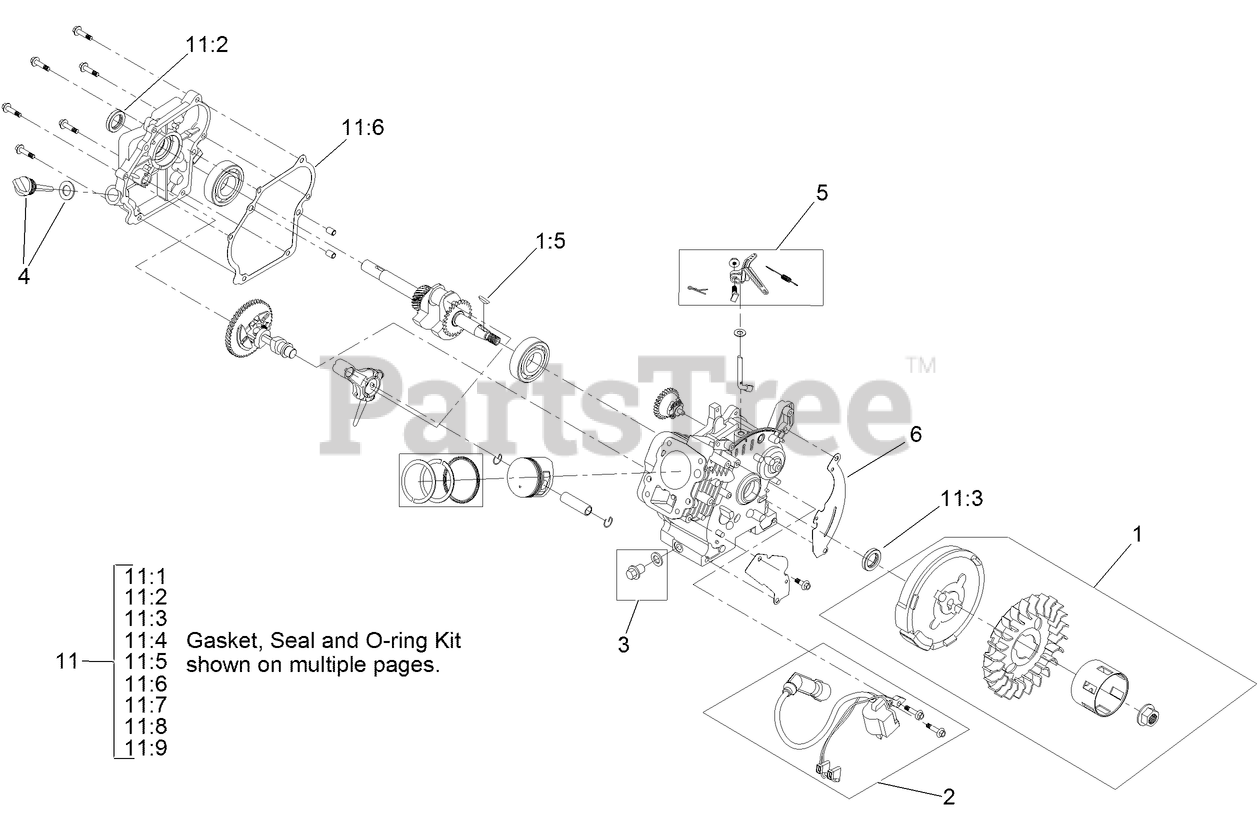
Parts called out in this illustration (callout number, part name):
1	FLYWHEEL AND FAN KIT
1:5	KEY-WOODRUFF
2	IGNITION KIT
3	DRAIN PLUG KIT
4	DIPSTICK AND O-RING KIT
5	GOVERNOR KIT
6	BLOWER SHROUD KIT
11	GASKET, SEAL AND O-RING KIT
11:1	GASKET-EXHAUST
11:2	SEAL-OIL
11:3	SEAL-OIL
11:4	GASKET-COVER, VALVE
11:5	GASKET-HEAD, CYLINDER
11:6	GASKET-COVER, CRANKCASE
11:7	GASKET-INSULATOR
11:8	INSULATOR-CARBURETOR
11:9	GASKET-CARBURETOR
